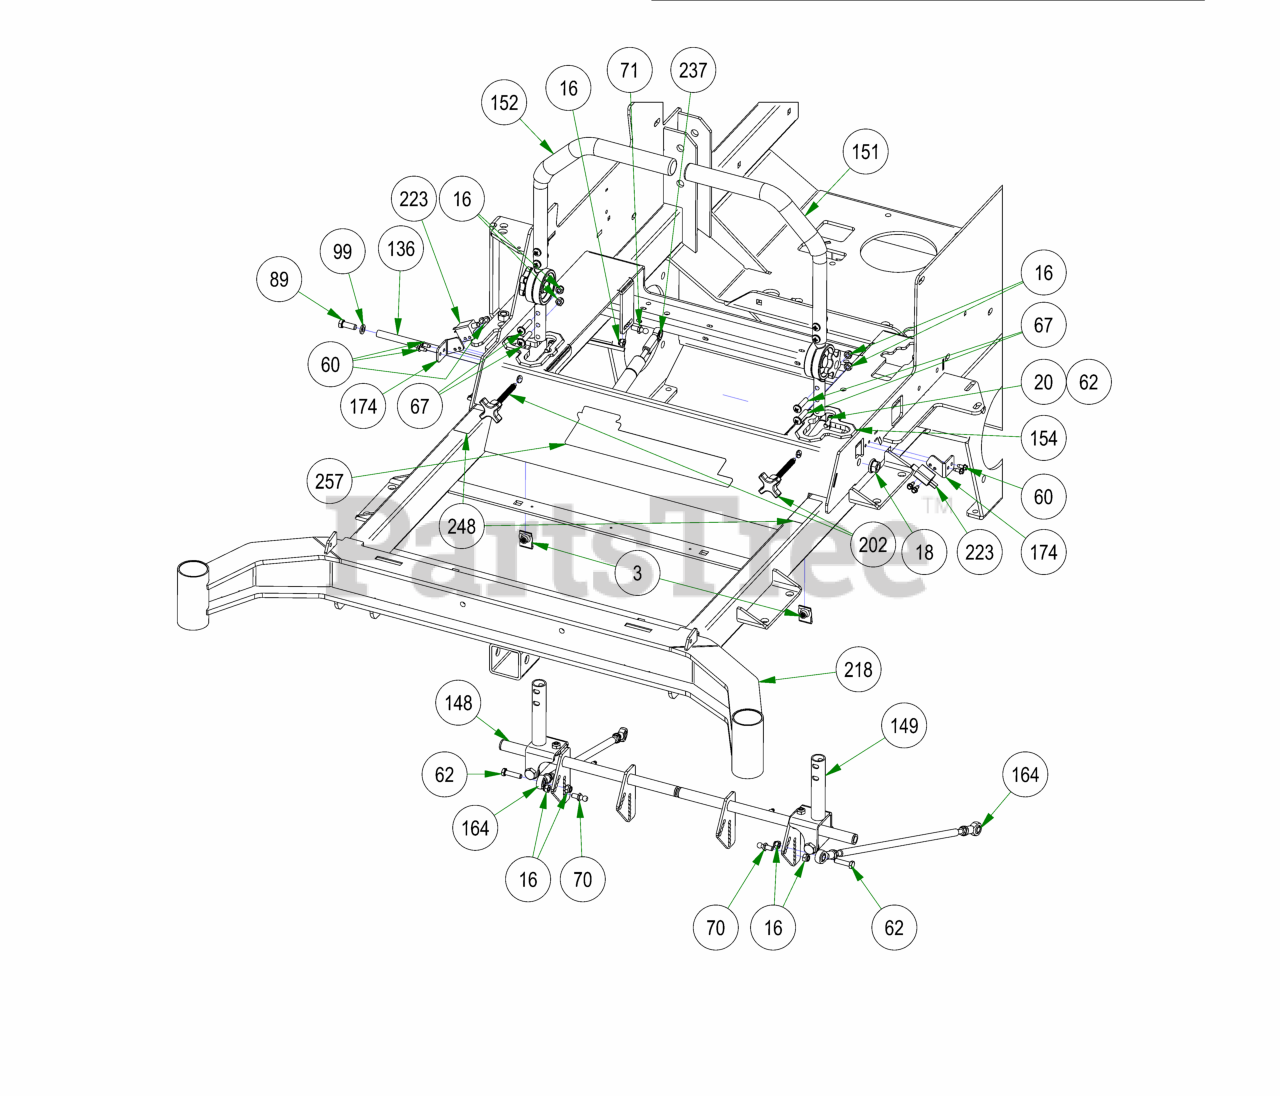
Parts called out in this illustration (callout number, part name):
3	Extruded Nut 3/8"-16 3/4" Hole Center With Patch
16	5/16-18 NYL INS L/N ZC
18	1/2-13 NYLON INSERT FLANGE LOCKNUT ZINC
20	5/16-18 HEX SERRATED FLANGE NUT HARD/ZINC
60	12-24 X 1/2 HEX WASHER UNLSOT F TCS ZINC
62	5/16-18 X 1-1/4 HEX C/S (GR.5) ZC
67	5/16-18 x 1 3/8" Futton Head Torx Drive Bolt
70	10mm Damper Ball Stud-Steering
71	10mm Damper Ball Stud-XP Linkage
89	3/8-16 X 1 GR 5 Hex Bolts Zinc
99	3/8 SPLIT LOCKWASHER ZINC
136	2019 Steering Actuator Rod
148	2019 R Series RH Arm Rod Assembly
148.7.1	1/4" Press in Grease Fitting
148.7.2	2019 Drive Arm Actuator right - Weldment
148.7.3	2019 Drive Arm Bushing
149	2019 R Series LH Arm Rod Assembly
149.7.1	1/4" Press in Grease Fitting
149.7.2	2019 Drive Arm Actuator left - Weldment
149.7.3	2019 Drive Arm Bushing
151	2019 Left Hand ADJ. Steering Arm Kit
152	2019 Right Hand ADJ. Steering Arm Kit
154	Snap-in Drive Arm Bushing
164	2019 Rebel Push Rod Assembly
174	2019 Arm Switch Bracket
202	Speed Limiting Knob 3/8-16X 3"
218	2022 Rebel Frame
223	Safety Switch
237	Steering Damper
248	2018 LH/RH Steering Control Decal Roll
257	2019 Rebel Cooler Cover Decal
